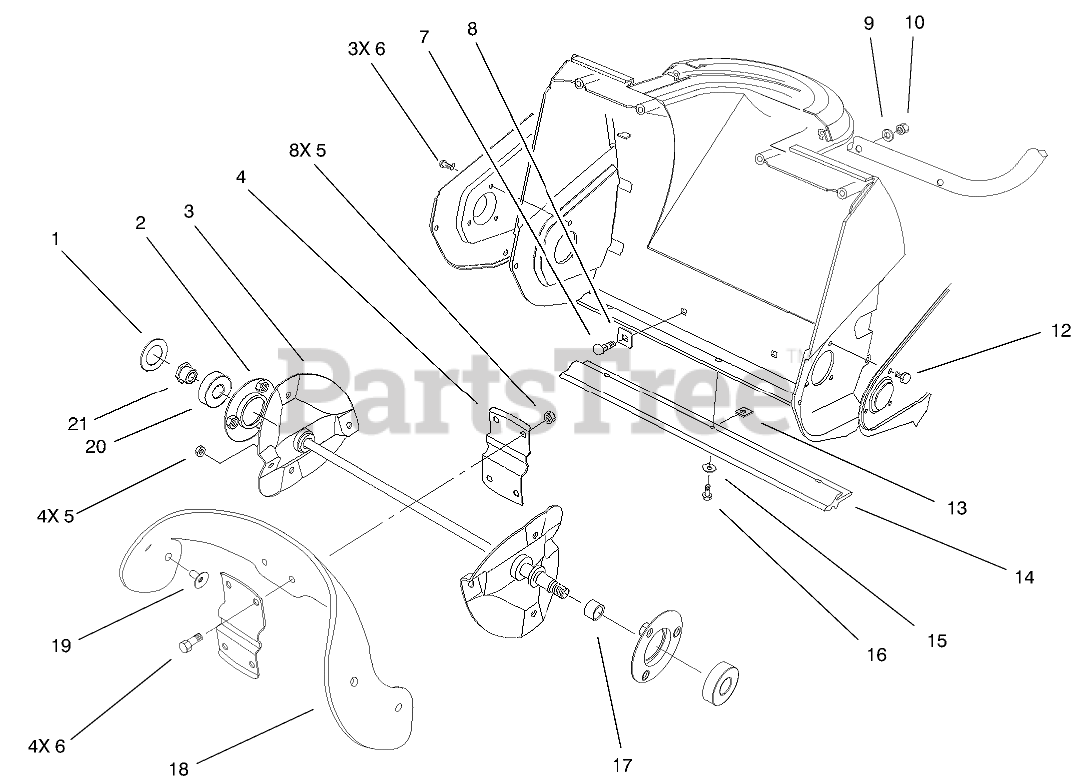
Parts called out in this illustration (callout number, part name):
1	WASHER-RUBBER
2	FLANGE BEARING ASM
3	ROTOR SHAFT ASM
4	SUPPORT-ROTOR
5	NUT-LOCK, NI
6	SCREW-HHF
7	SCREW-CARR
8	WASHER-SQUARE
9	WASHER
10	NUT-LOCK, NI
12	SCREW-HH
13	NUT-CLIP, U
14	SCRAPER
15	WASHER-FLAT
16	SCREW-HWHTF
17	SPACER
18	BLADE-ROTOR
19	SCREW
20	BEARING-BALL
